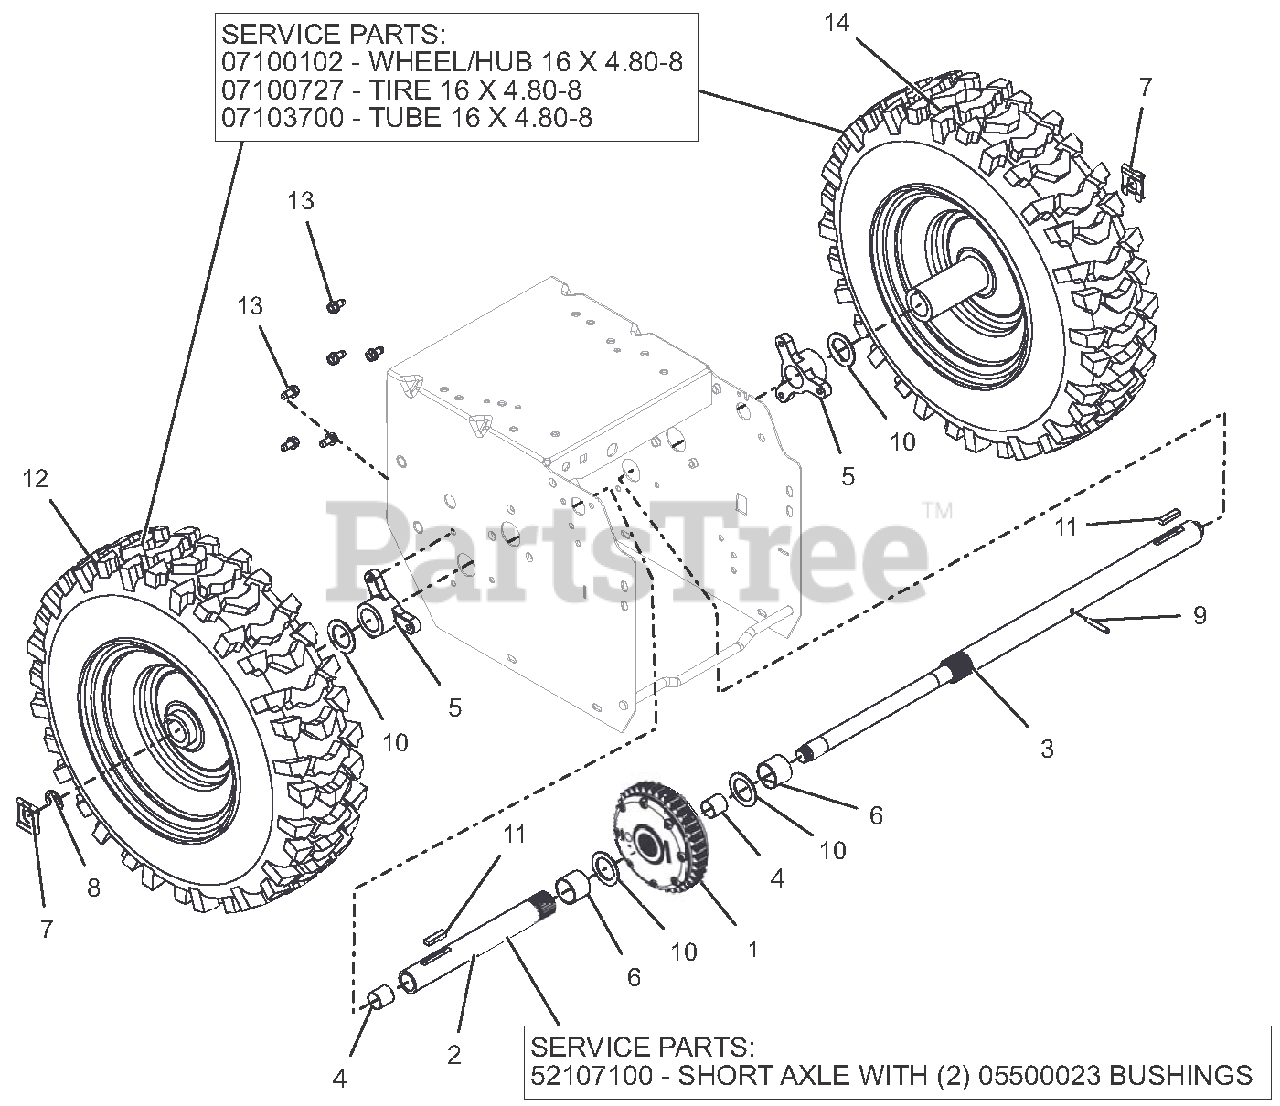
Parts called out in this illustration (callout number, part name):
1	DIFFERENTIAL, AUTOMATIC
2	BSHG-SLV .706X.764X.75 BRZ
2	KIT, SHORT AXLE W/BUSHINGS
3	AXLE, LONG - DIFFERENTIAL
4	BSHG-SLV .706X.764X.75 BRZ
5	BUSHING, AXLE
6	BSHG-SLV, 1.012X1.125X.875
7	CLIP, SNAP .625 DIA
8	RG-RTNG-EXT .625X.042
9	PIN-ROLL .188X1.25
10	WSHR-FL-STL 1.010X1.505X.062YZ
11	KEY-RECT .25X.188X1.00
12	TUBE
12	HUB, WHEEL - 16X4.8-8 DIFF
12	TIRE/WHEEL,RH 16X4.8-8 DIFF T2
12	TIRE, 4.80-8 K478
13	SCR-TAP .25-20X.50 HWH TR YWZ
14	TUBE
14	HUB, WHEEL - 16X4.8-8 DIFF
14	TIRE/WHEEL,LH 16X4.8-8 DIFF T2
14	TIRE, 4.80-8 K478
